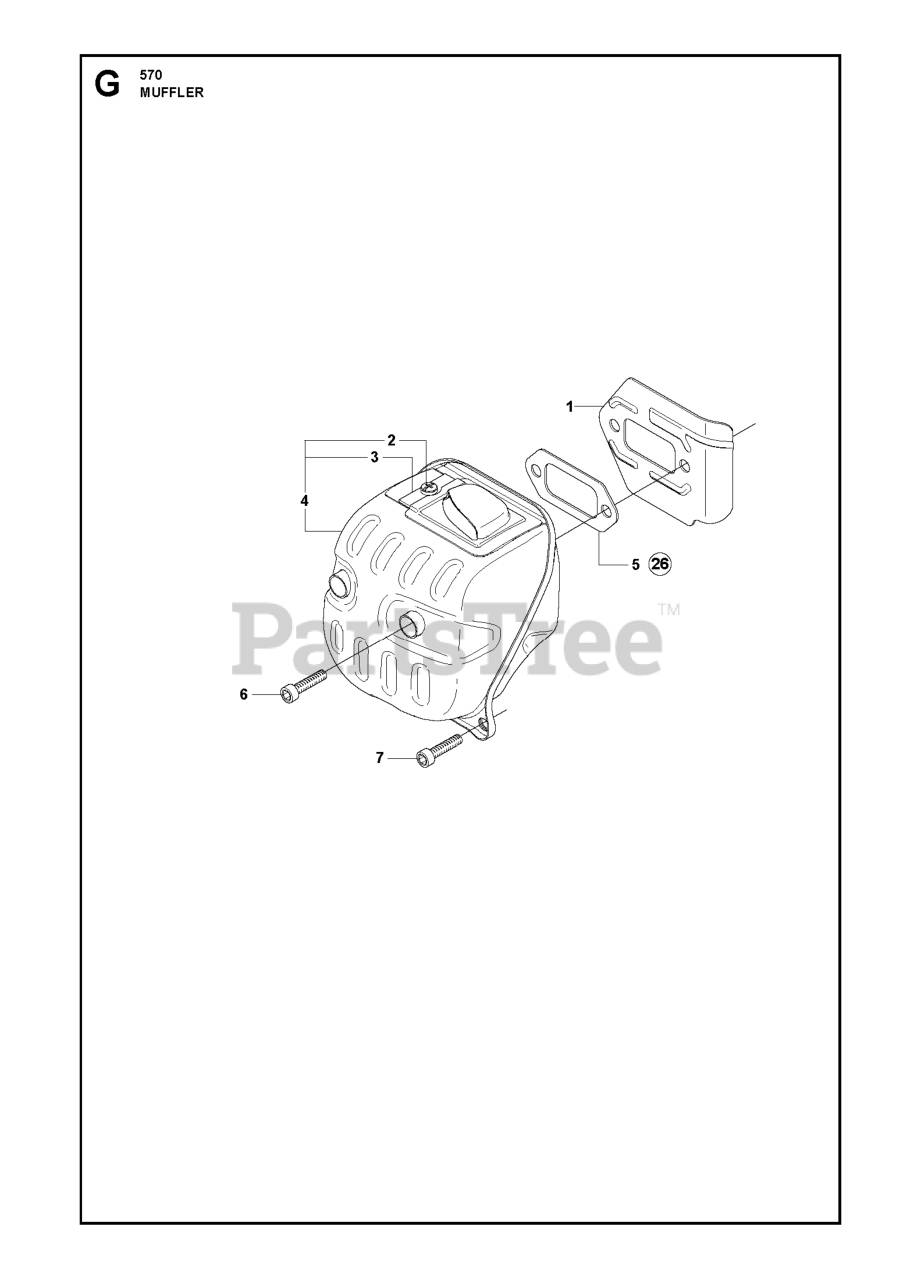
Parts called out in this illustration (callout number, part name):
4	MUFFLER ASSY (FF CE)
4	MUFFLER ASSY (DF US)
6	SCREW MC6S 6X20
26	GASKET SET
